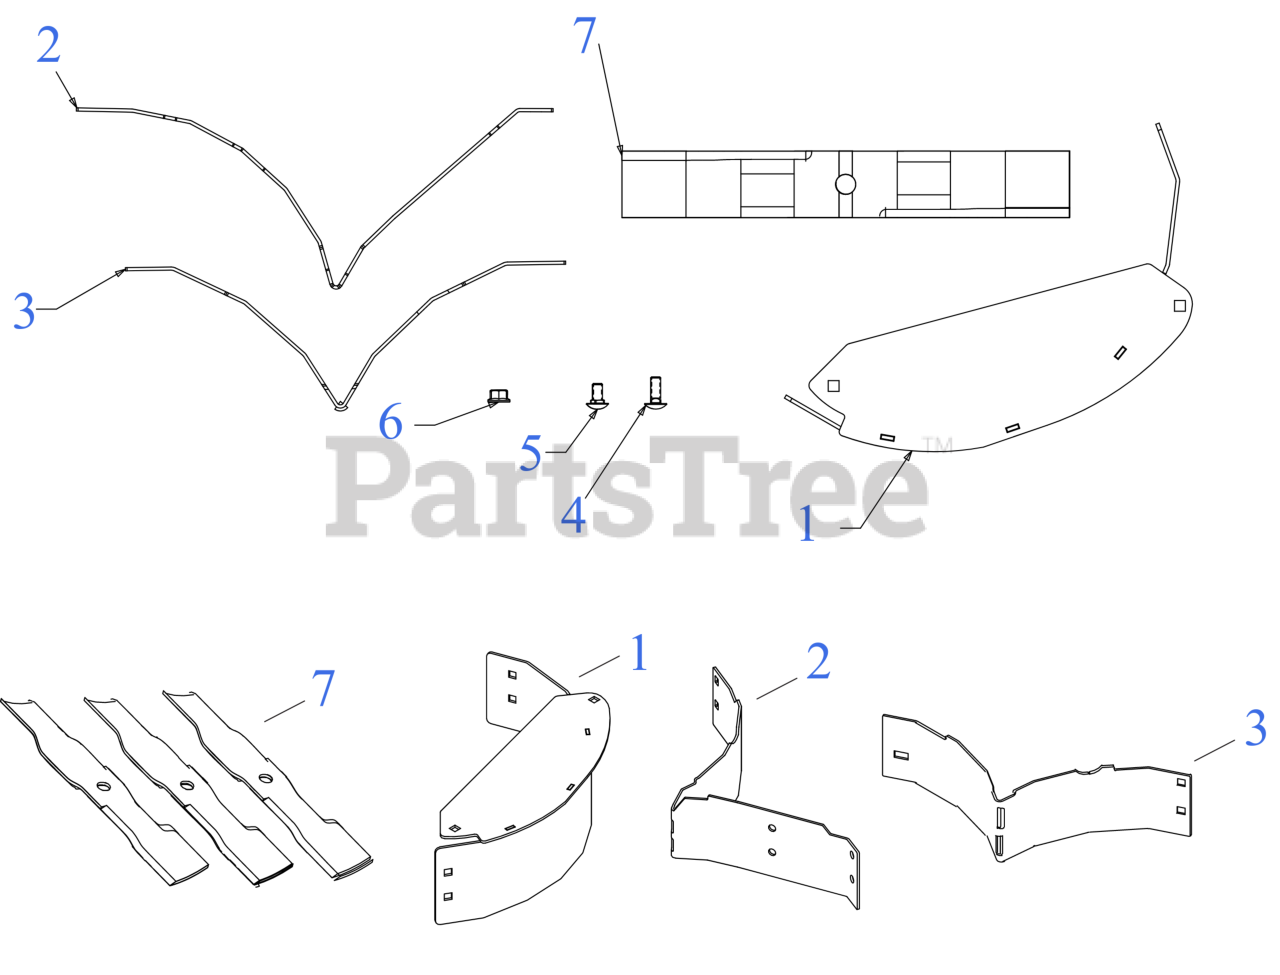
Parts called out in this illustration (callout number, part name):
1	48" DISCHARGE MULCH BAFFLE
4	CARRIAGE BOLT 3/8-16 x 1.00 GR5
5	CARRIAGE BOLT 3/8-16 x .75
6	NUT-CTRLCK FLG HEX
7	17" BLADE (MULCH)
